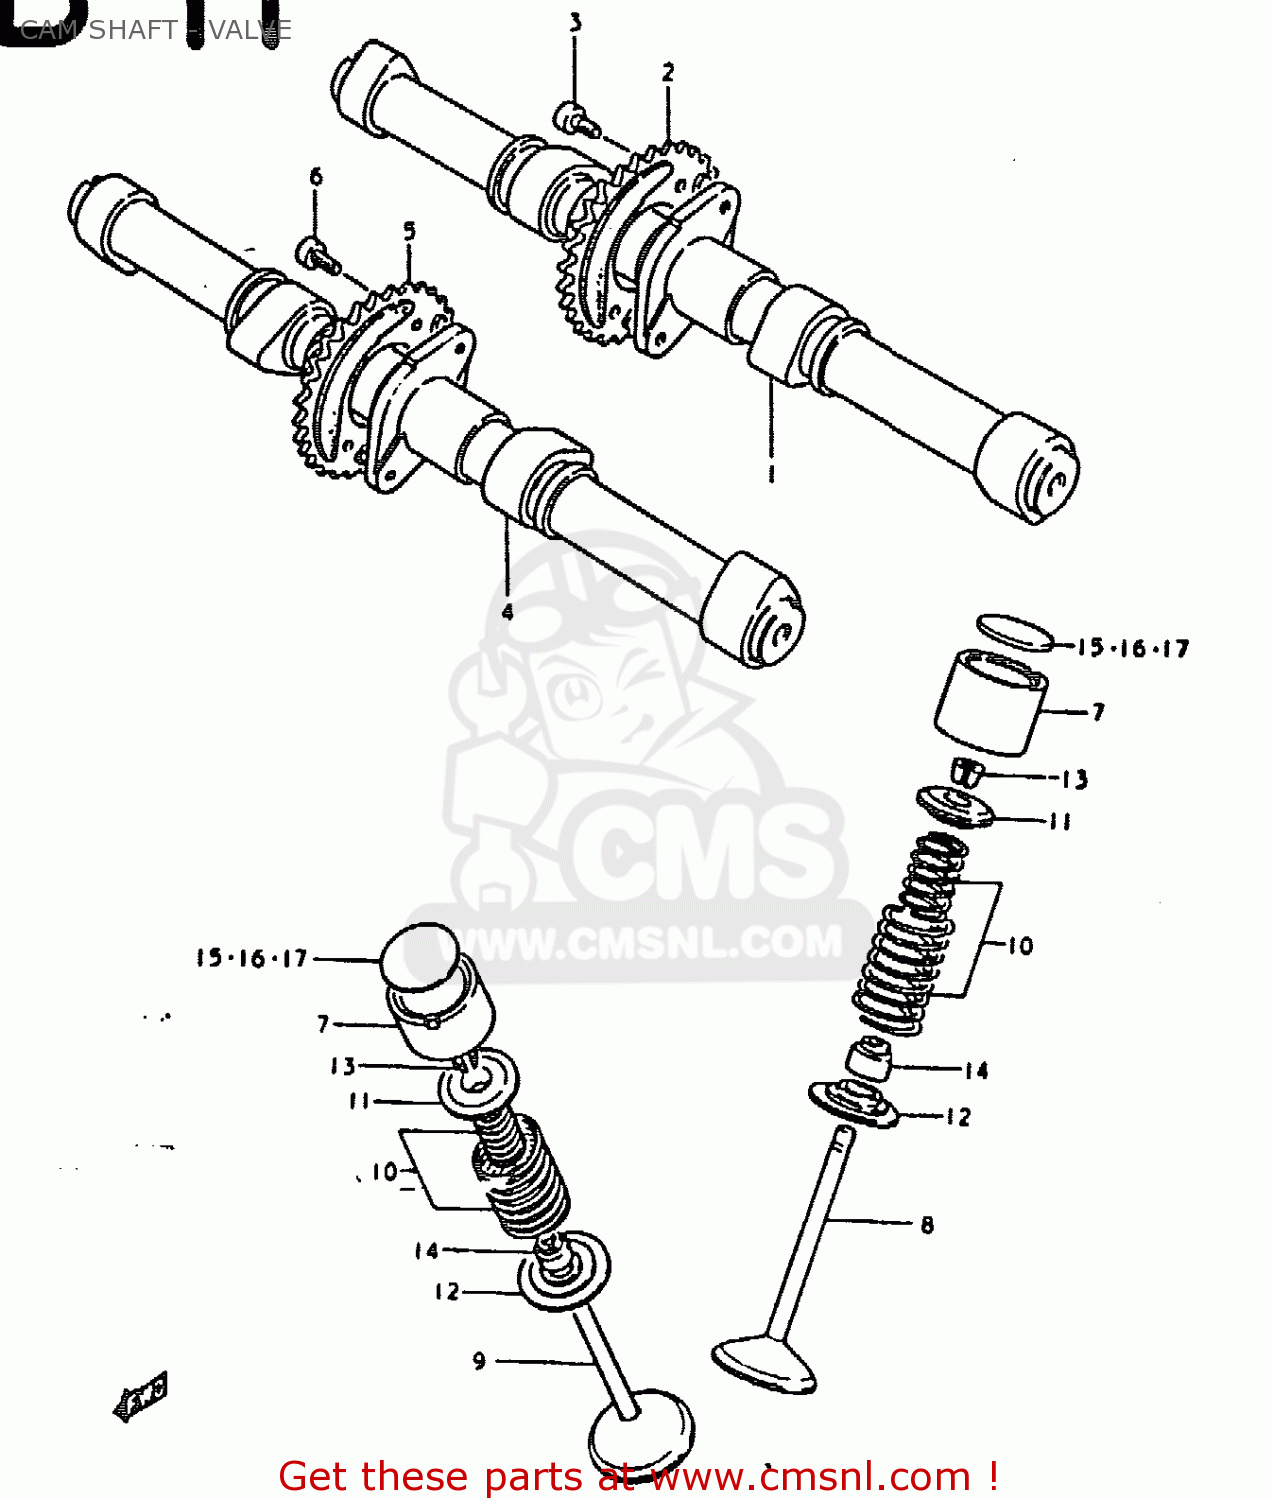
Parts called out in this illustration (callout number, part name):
1	CAMSHAFT
2	SPROCKET,CAMSHAFT
3	BOLT 6X11
4	CAMSHAFT,EXHAUST
5	SPROCKET,EXHAUST CAMSHAFT
6	BOLT 6X11
7	TAPPET
8	VALVE,INTAKE
9	VALVE,EXHAUST
10	SPRING SET,VALVE
11	RETAINER,VALVE SPRING
12	SEAT,VALVE SPRING
13	SHIM,TAPPET
14	SEAL,OIL(7X14.4X9)
15	SHIM,TAPPET
16	SHIM,TAPPET
17	SHIM,TAPPET
